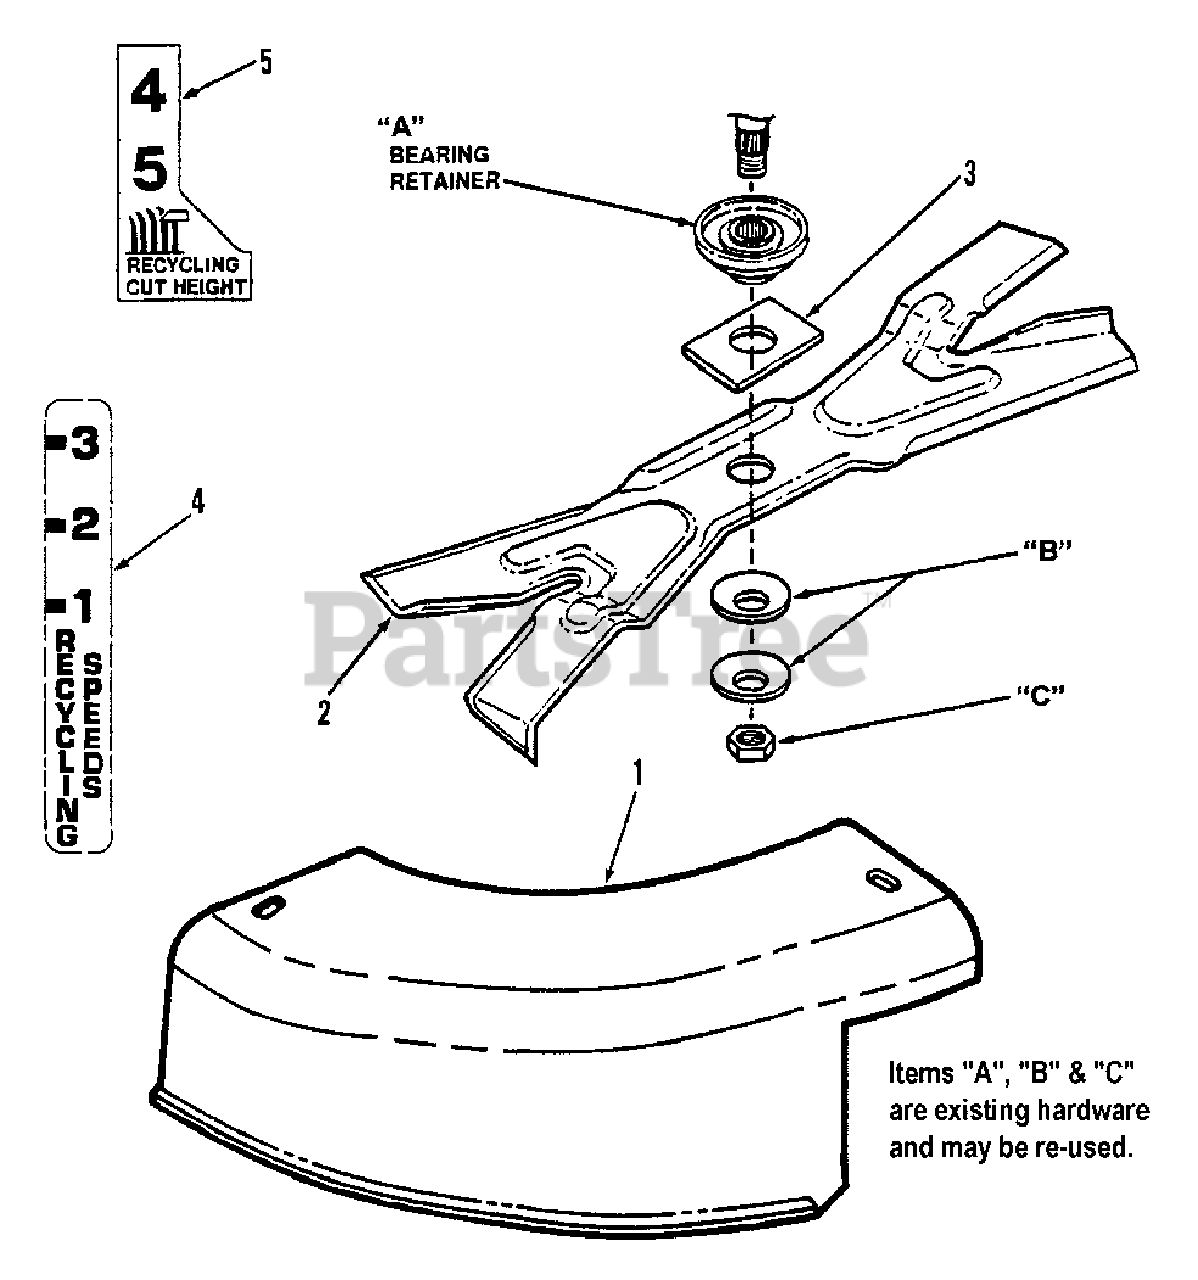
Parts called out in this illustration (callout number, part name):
1	COVER, 38" Mulching Deck
2	BLADE, 19-1/2" Ninja
3	WASHER, Ninja Blade
4	DECAL, Recycling Ground Speed
5	DECAL, Height of Cut
